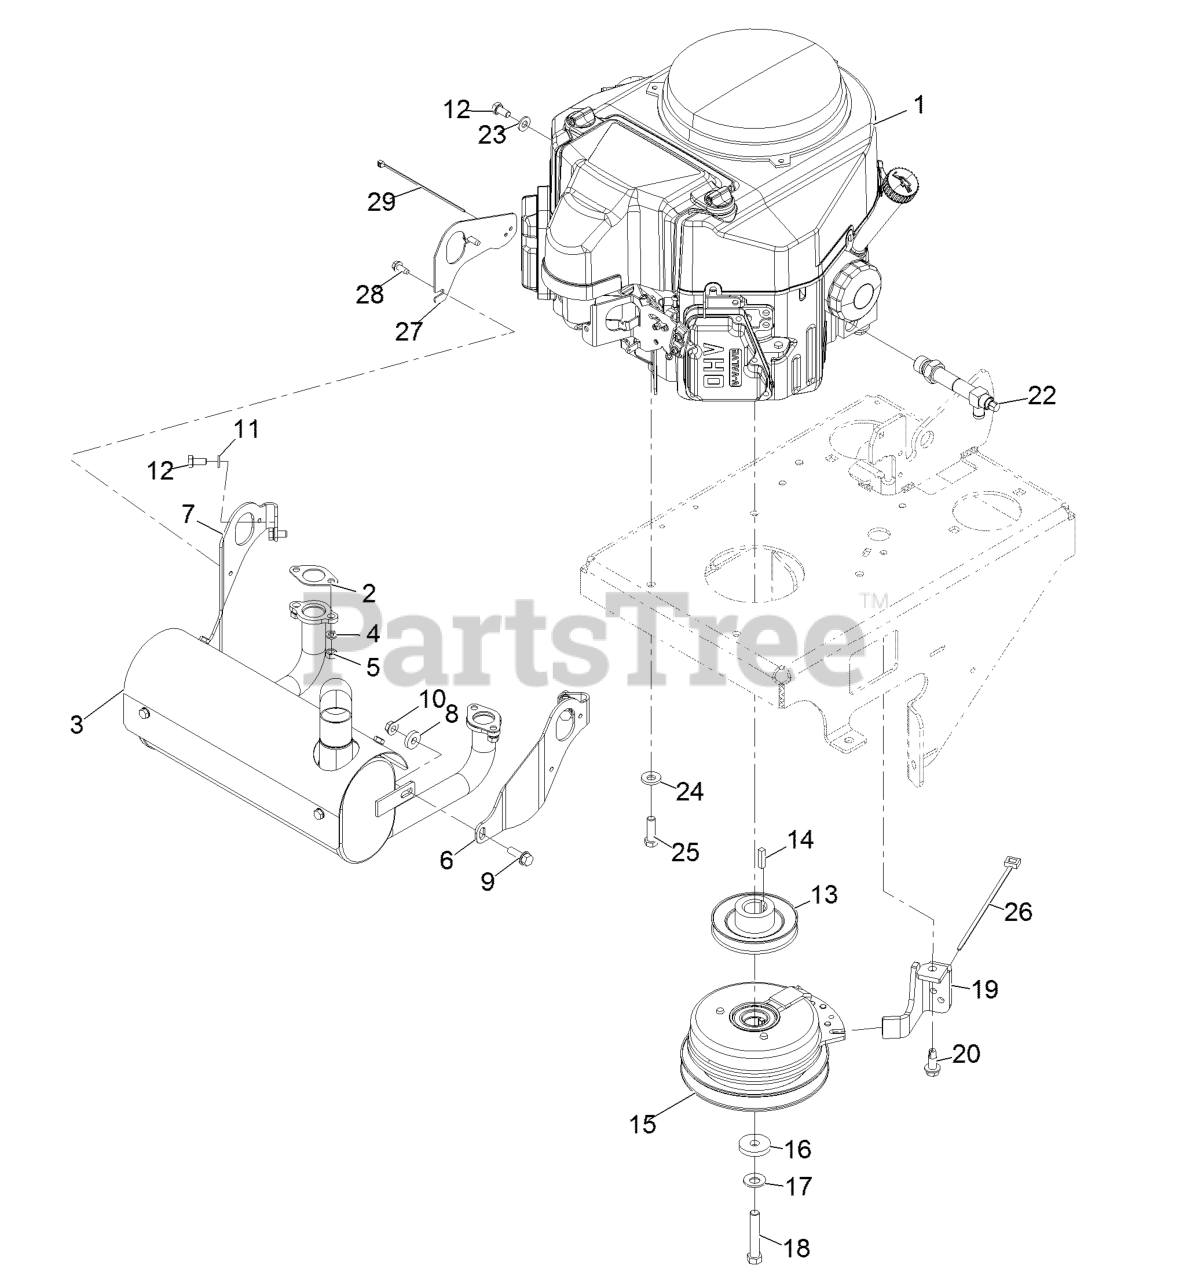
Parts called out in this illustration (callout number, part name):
2	GASKET-EXHAUST
4	WASHER-LOCK
6	BRACKET-MUFFLER MOUNT, LH
7	BRACKET-MUFFLER MOUNT, RH
9	SCREW-HHF
11	WASHER-LOCK
12	SCREW-HH
13	PULLEY
15	CLUTCH-175 FT-LB
16	WASHER
17	WASHER-SPRING
18	SCREW-HH
19	ANCHOR-CLUTCH
20	SCREW-TAPPING
22	DRAIN-OIL, VALVE, KAW
23	WASHER-PLAIN
24	WASHER-BELLEVILLE
25	SCREW-HH
26	TIE-CABLE
27	GUARD-CABLE, SPARK PLUG
28	SCREW-HWH
29	TIE-CABLE
